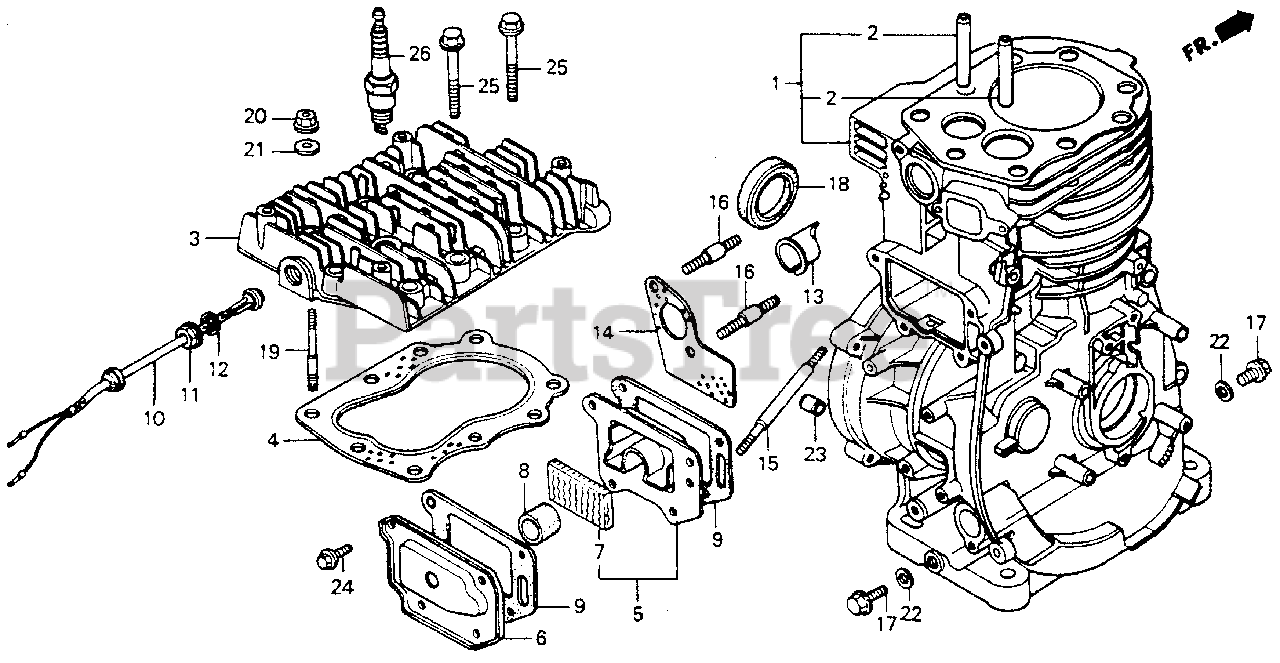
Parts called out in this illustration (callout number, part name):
2	GUIDE, VALVE
3	CYLINDER HEAD (NOT AVAILABLE)
4	GASKET, CYLINDER HEAD
5	CASE, BREATHER
6	COVER, TAPPET
7	FILTER, BREATHER
8	SEAL, BREATHER
9	GASKET, TAPPET COVER
10	SWITCH ASSY., THERMOSTAT (NOT AVAILABLE)
11	BOSS, THERMOSTAT SWITCH (NOT AVAILABLE)
12	WASHER, SWITCH BOSS
13	LINER, EX. PIPE
14	GASKET, MUFFLER
15	BOLT, STUD (8X104)
16	BOLT, STUD (8X35)
17	BOLT, DRAIN PLUG
18	OIL SEAL (30X46X8)
19	BOLT, STUD (10X70)
19	BOLT, STUD (10X60)
19	BOLT, STUD (10X40)
20	NUT, FLANGE (10MM)
21	WASHER, PLAIN (10MM)
22	WASHER, DRAIN PLUG (12MM)
23	PIN A, DOWEL (8X14)
24	BOLT, FLANGE (6X10)
25	BOLT, FLANGE (10X55)
26	SPARK PLUG (BPR-4HS-10) (NGK)
26	SPARK PLUG (BPR4HS-10) (NGK)
26	SPARK PLUG (W14FP-UL10)
26	SPARK PLUG (W14FPR-UL10)
